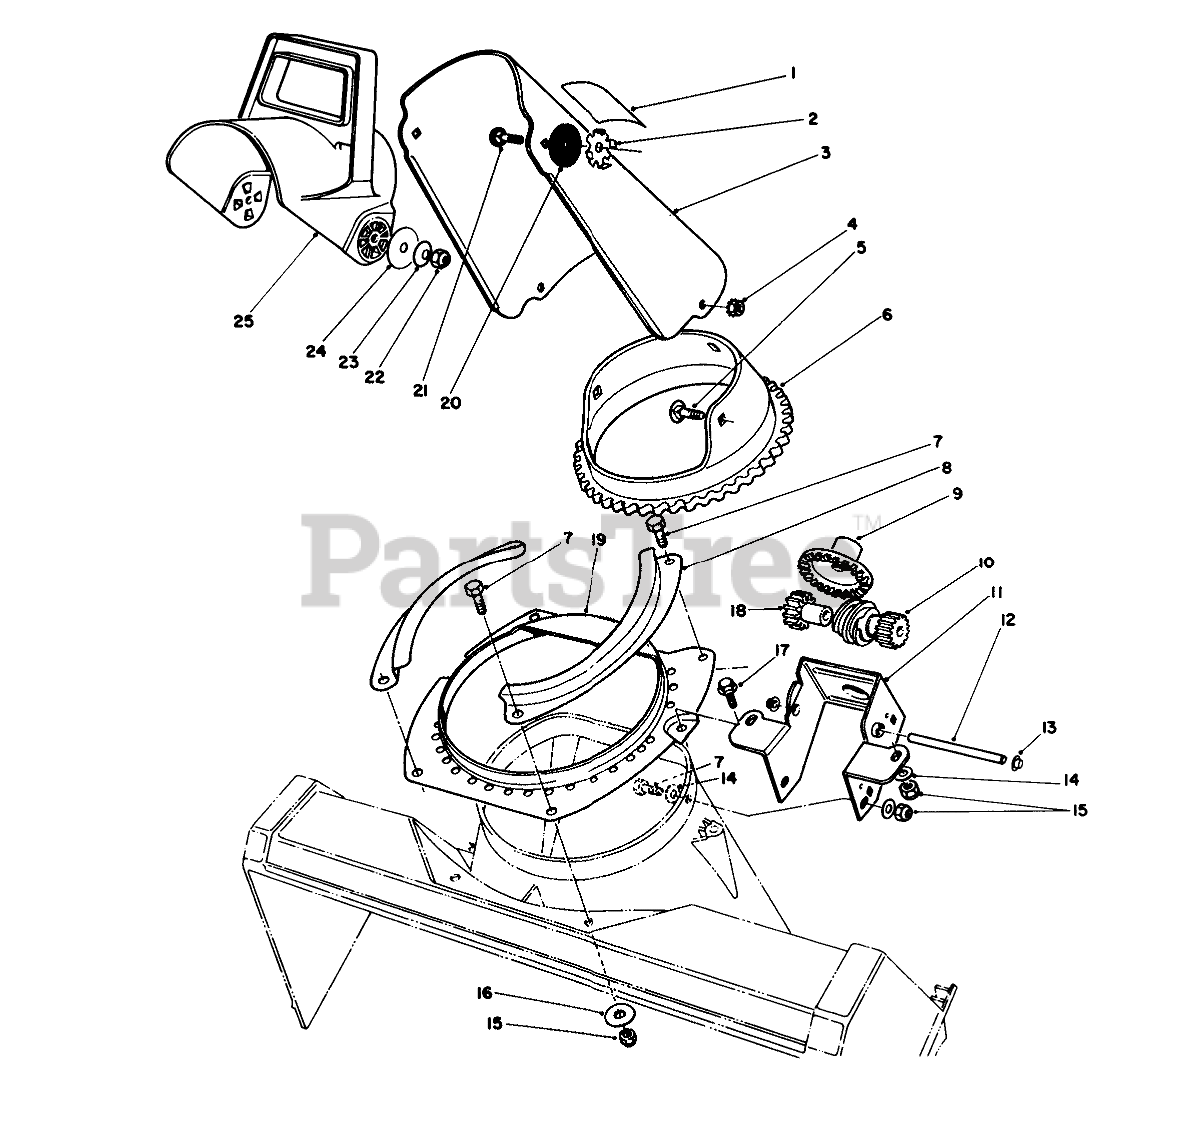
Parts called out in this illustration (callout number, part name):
1	Decal-Danger
2	PLATE-FRICTION
3	Chute-Discharge (Incl. Ref. #1:63-3760)
4	NUT-KEPS
5	SCREW-CARR
6	RING-GEAR, CHUTE
7	SCREW-HH
8	Retainer-Chute Ring
9	GEAR-FACE
10	GEAR-SPUR/WORM
11	Bracket-Chute Gear
12	SHAFT-GEAR, WORM
13	NUT-PUSH
14	WASHER-FLAT
15	NUT-LOCK, NI
16	WASHER-FLAT
17	SCREW-PLASTITE
18	GEAR-SPUR, SPACER
19	Ring-Chute Support
20	WASHER-RUBBER
21	SCREW-CARR
22	NUT-LOCK, NI
23	WASHER-BELLEVILLE
24	WASHER-FLAT
25	CHUTE-DEFLECTOR
